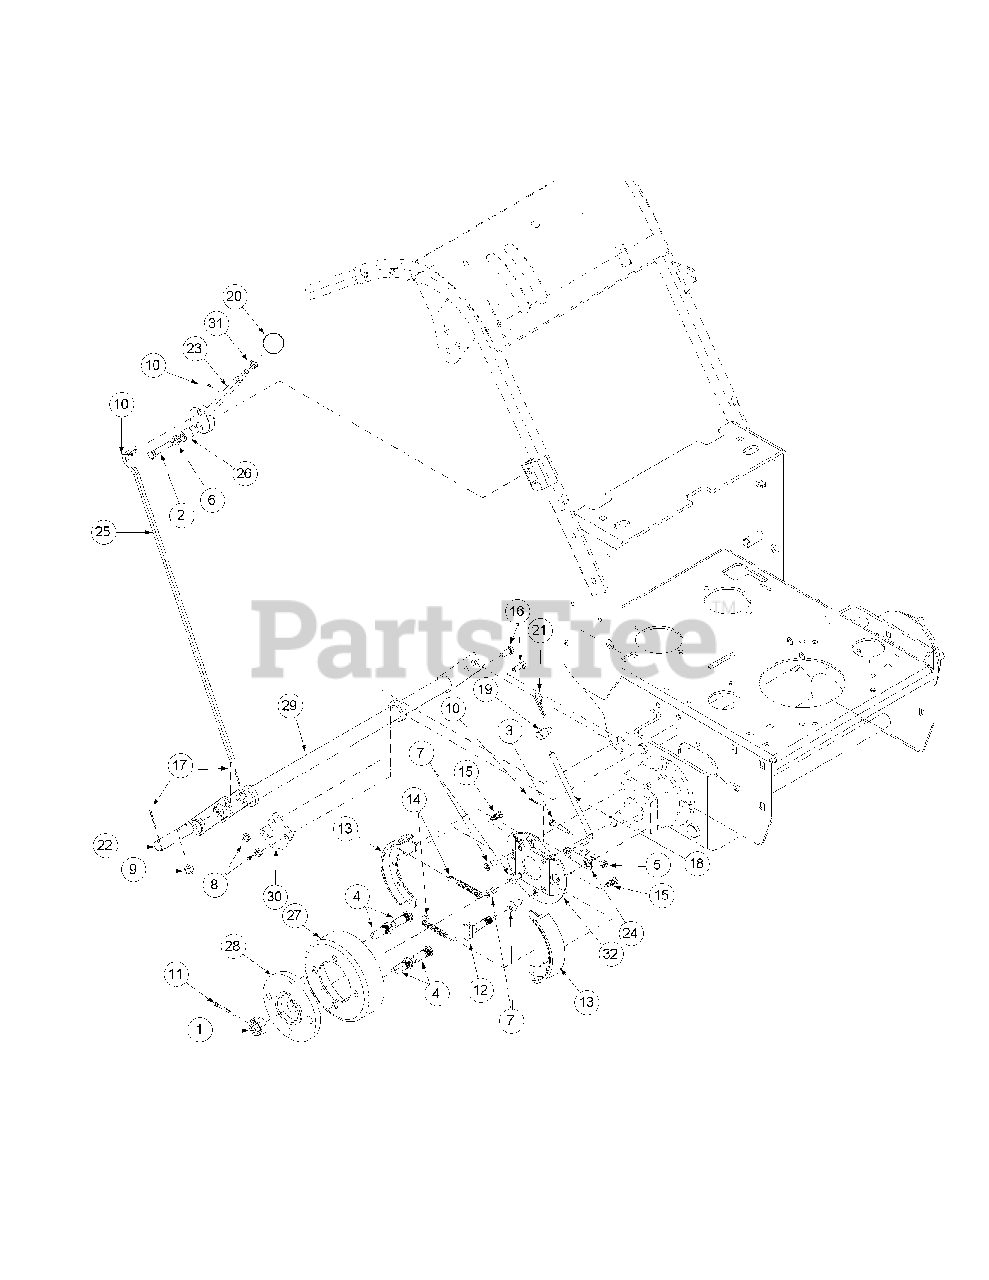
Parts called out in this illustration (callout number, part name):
1	Nut, Castle, 3/4-16
2	Capscrew, 3/8-16 x 1" Grade 5 Zinc
3	Cap Screw, 1/4-20 x 1.50, Grade 5
4	Bolt, Wheel, 1/2-20 x 1-3/8
5	Lock Nut, Nylon Insert, 1/4-20 Grade A
6	Lock Washer, 3/8 Zinc
7	Capscrew, Socket Button Hd., 3/8-16 x 3/4 Zinc
8	Nut, 5/16-18, Nylock
9	Nut, Nylon Insert, 3/8-16 Grade A
10	Cotter Pin, 3/32 x 3/4, Zinc
11	Cotter Pin, 5/32 x 1-1/2 Zinc
12	Brake Cam, Actuating
13	Brake Shoe w/Lining, 6 x 1-1/4
14	Brake Spring, Tension
15	Brake Spring, Anti-Vibration
16	Cap Screw, 5/16-18 x 3/4, Grade 5
17	Cotter Pin, 3/32 x 1, Zinc
18	Brake Rod
19	Swivel Joint
20	Knob, Red, Shift w/Insert
21	Hair Pin, 3/8"-1/2"
22	Joint, Brake Pull
23	Lever Assembly, Brake
24	Brake Clamp, Control Assembly, Hydro
25	Rod, Long Brake, Hydro WB
26	Pivot Spacer, Hydro WB
28	Hub, Wheel Motor
29	Brake Pivot Shaft Assembly
30	Pivot Mount, Brake
31	Nut, 3/8-16, Jam, Grade 2
32	Brake Backing Plate
